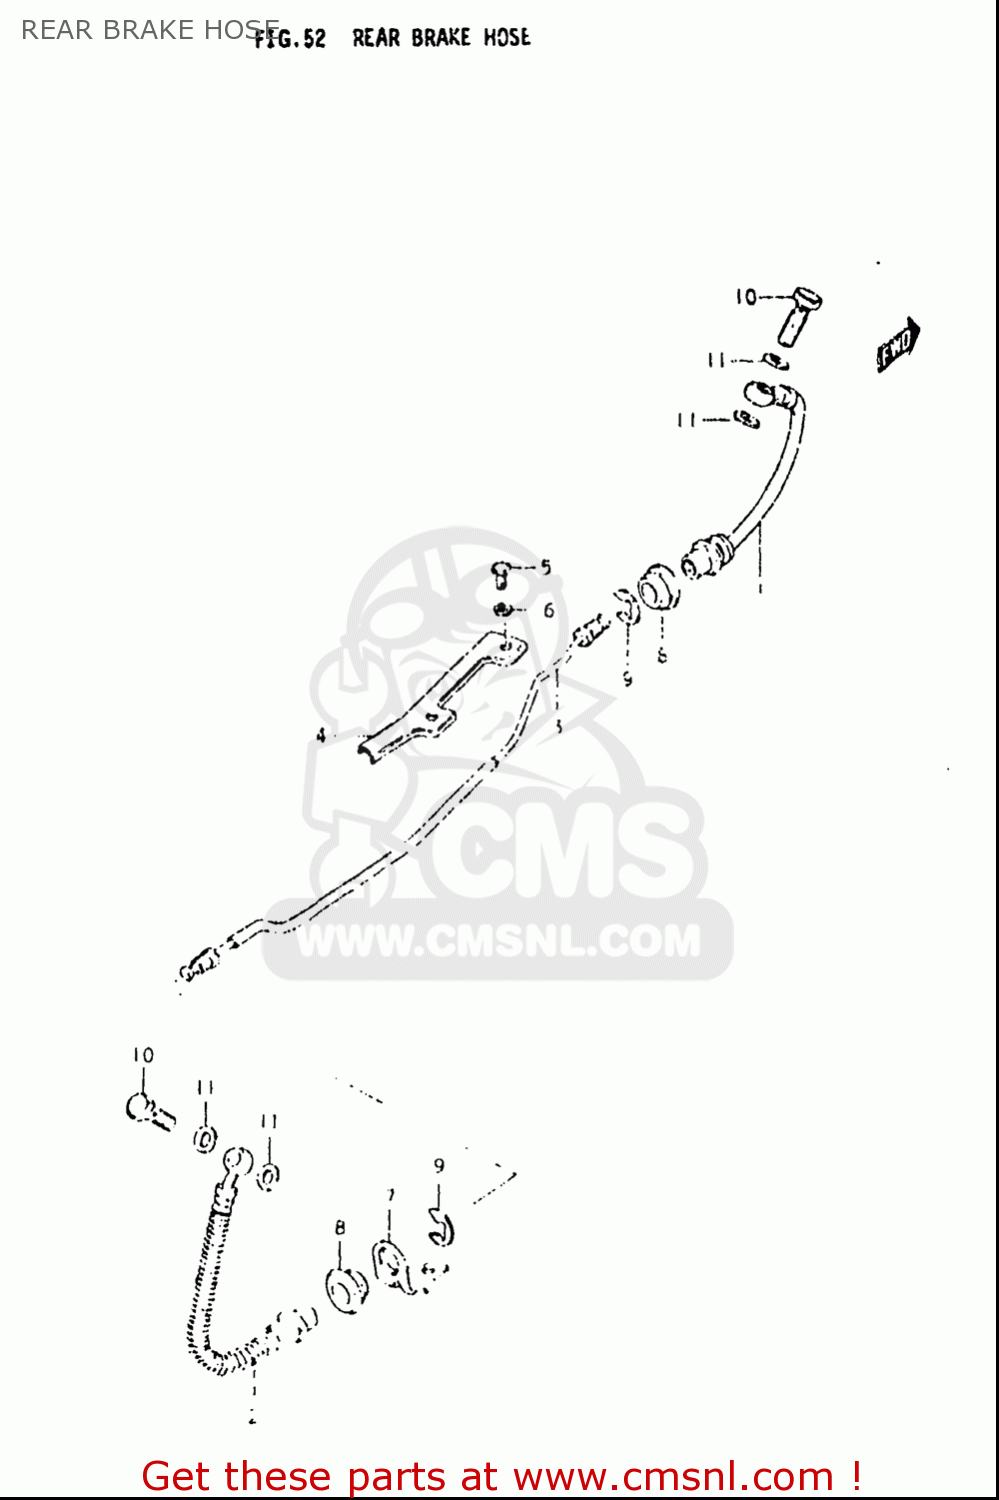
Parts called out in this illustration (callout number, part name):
2	HOSE,RR BRAKE NO.2
3	PIPE,REAR BRAKE
4	COVER,REAR BRAKE PIPE
5	BOLT(6X8)
6	LOCK WASHER
7	GUIDE,BRAKE HOSE
8	GROMMET,BRAKE HOSE GUIDE
9	E RING
10	BOLT UNION
11	WASHER(10X15X1.5)
